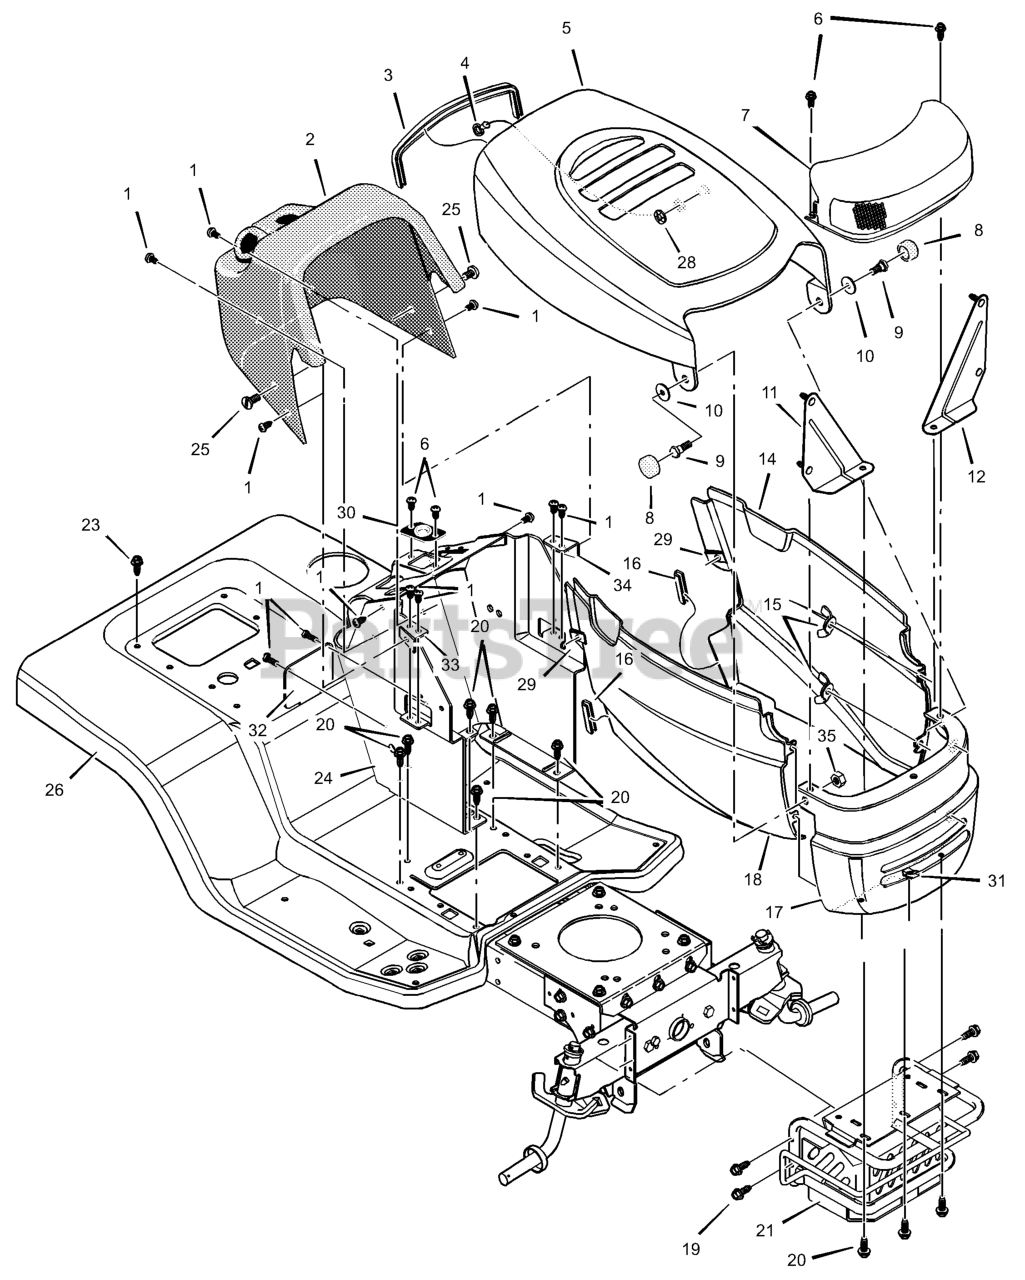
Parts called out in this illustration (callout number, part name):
1	Screw
3	Trim 26 3/4"
5	Hood Assembly
7	Lens & Reflector Assembly
8	Cap, Pivot
9	Bolt, Shoulder
10	Base, Pivot
11	Brace, Right Grille Assembly
12	Brace, Left Grille Assembly
14	Panel, Left Side
15	Wingnut
16	Trim 4 3/4"
18	Panel, Right Side
21	Mount, Grille/Bumper
26	Deck Seat
29	Cap, Push
30	Bearing, Steering
32	Panel, Access
33	Bracket, Right Console
34	Bracket, Left Console
35	Nut
